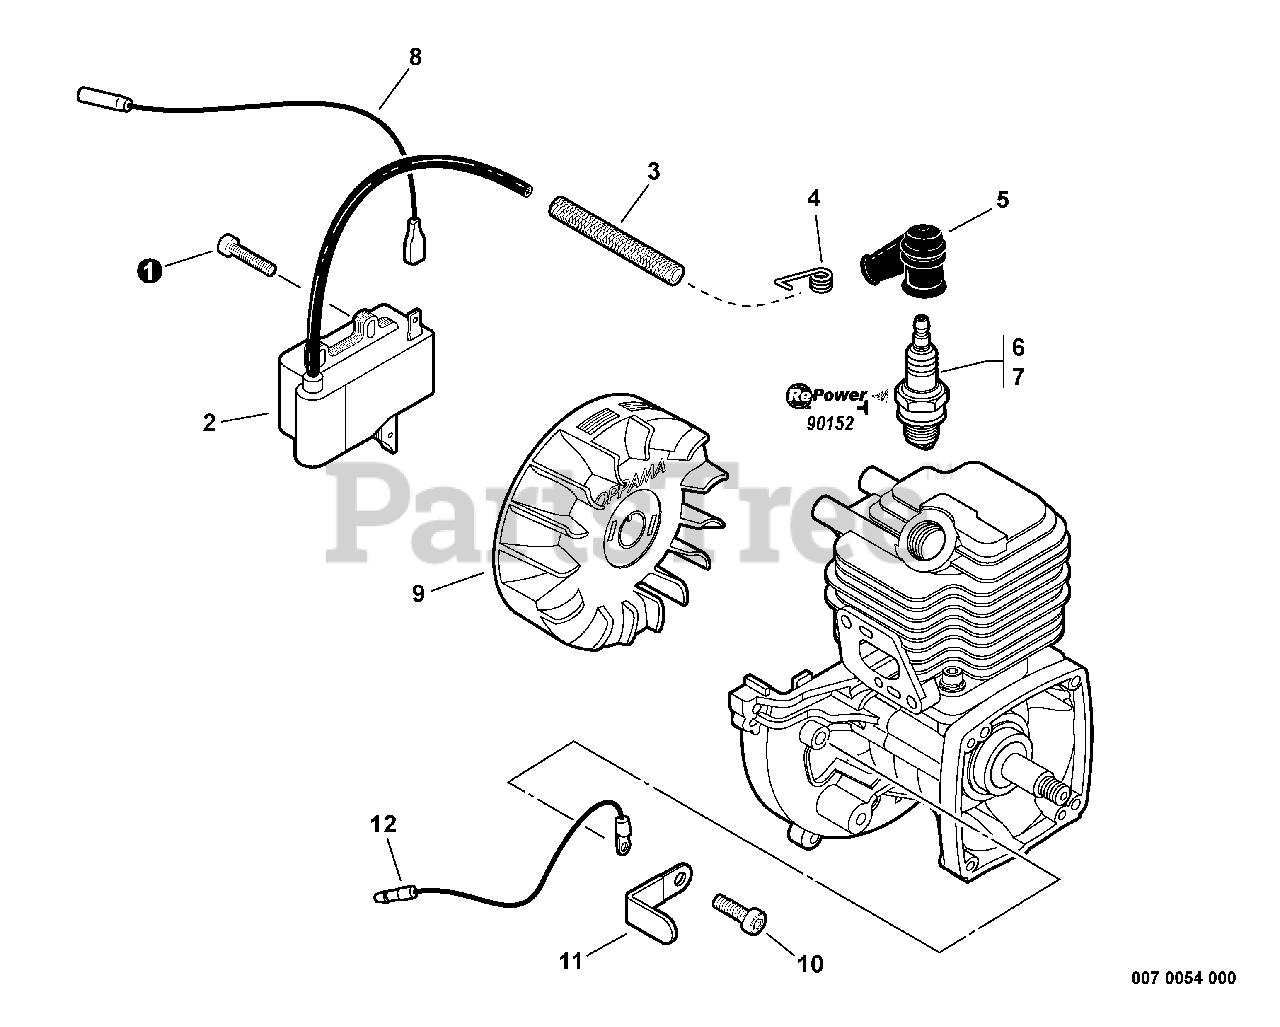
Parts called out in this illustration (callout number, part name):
1	BOLT, TORX 4×20
2	COIL, IGNITION
3	TUBE, INSULATOR Ø8 L= 65
4	TERMINAL, SPARK PLUG
5	CAP, SPARK PLUG
6	SPARK PLUG - BPM8Y
7	SPARK PLUG - BPMR8Y
8	LEAD - IGNITION L= 210
9	FLYWHEEL
10	BOLT, TORX 5×10
12	LEAD - GROUND L= 115
TU	TUNE-UP KIT - REPOWER
